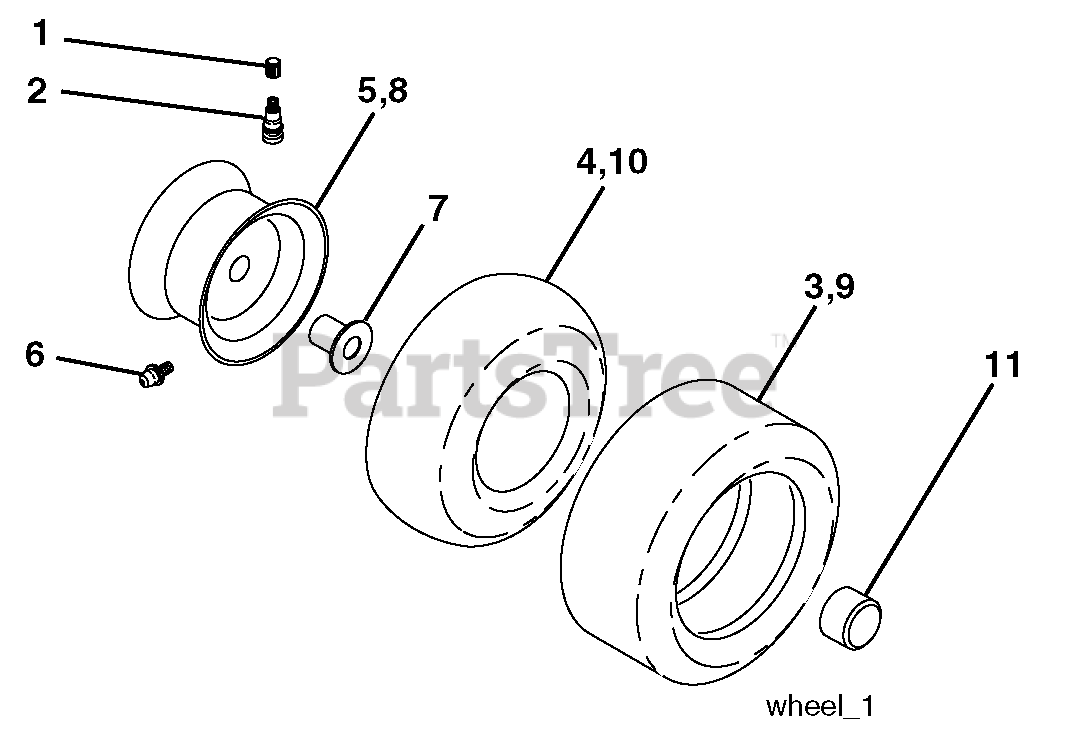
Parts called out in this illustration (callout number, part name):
1	Cap, Tire Valve
2	Stem, Valve
3	Tire, Front
4	Tube, Front
5	Rim Assembly, 6" Front
6	Fitting, Grease
7	Bearing, Flange
8	Rim Assembly, 8" Rear
10	Tube, Rear
11	Cap, Hub Axle
11	Sealant, Tire (10 oz. Tube)
